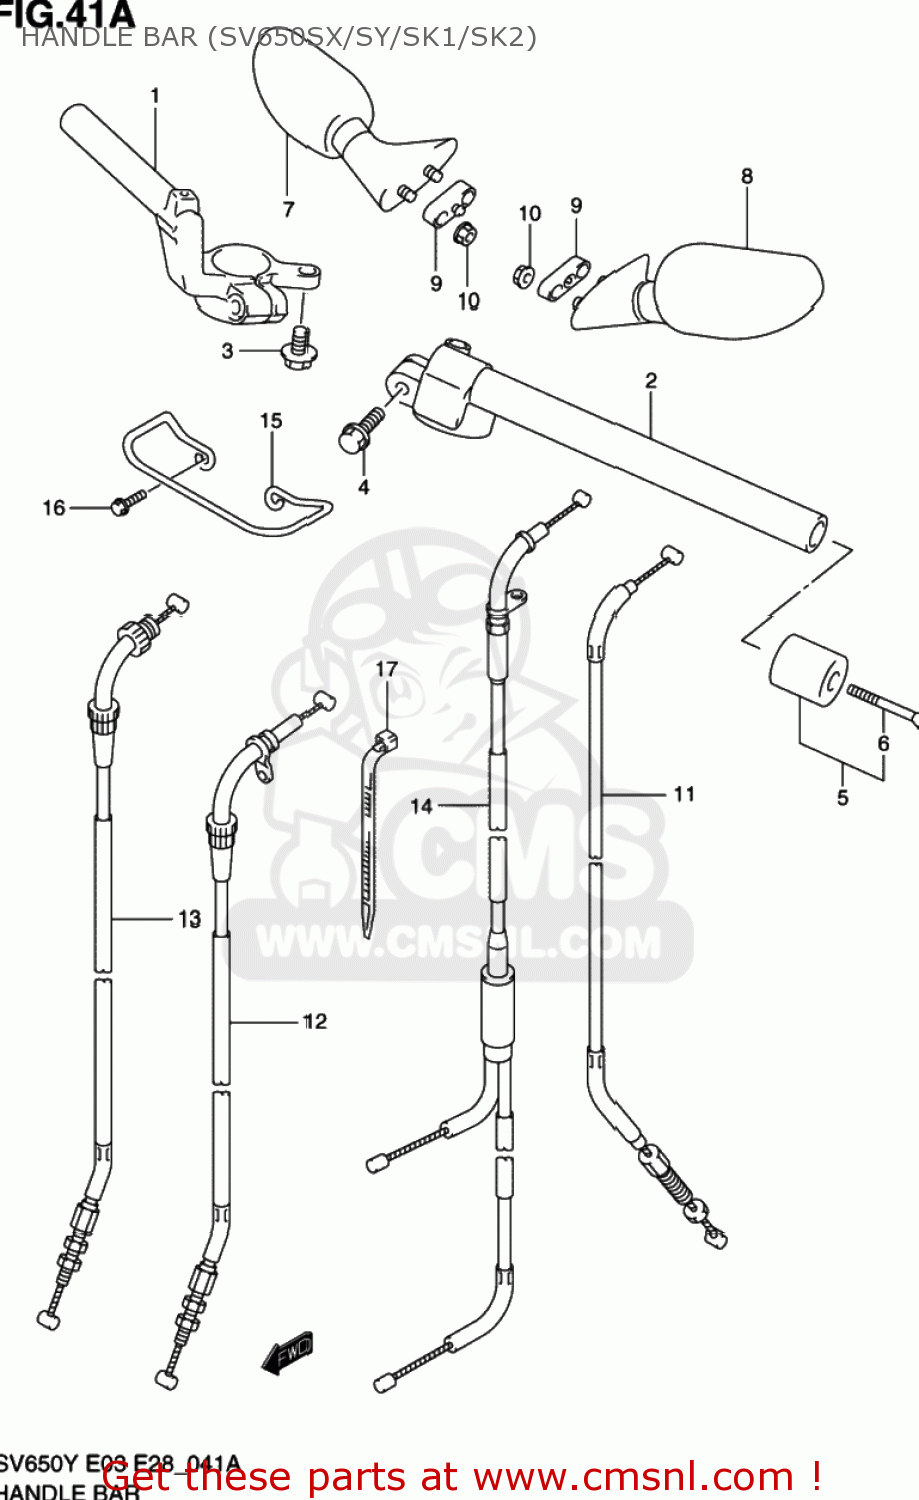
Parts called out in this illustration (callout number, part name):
1	HANDLEBAR,R
2	HANDLEBAR,L
3	BOLT
4	BOLT(8X30)
5	BALANCER SET,HANDLEBAR
6	SCREW
7	MIRROR ASSY,RR VIEW,R
8	MIRROR ASSY,RR VIEW,L
9	CUSHION,RR VIEW MIRRORR
10	NUT,RR VIEW MIRROR
11	CABLE ASSY,CLUTCH
12	CABLE ASSY,THROTTLE NO.1
13	CABLE ASSY,THROTTLE NO.2
14	CABLE,STARTER
15	GUIDE,CABLE
16	BOLT
17	CLAMP(L:145)
